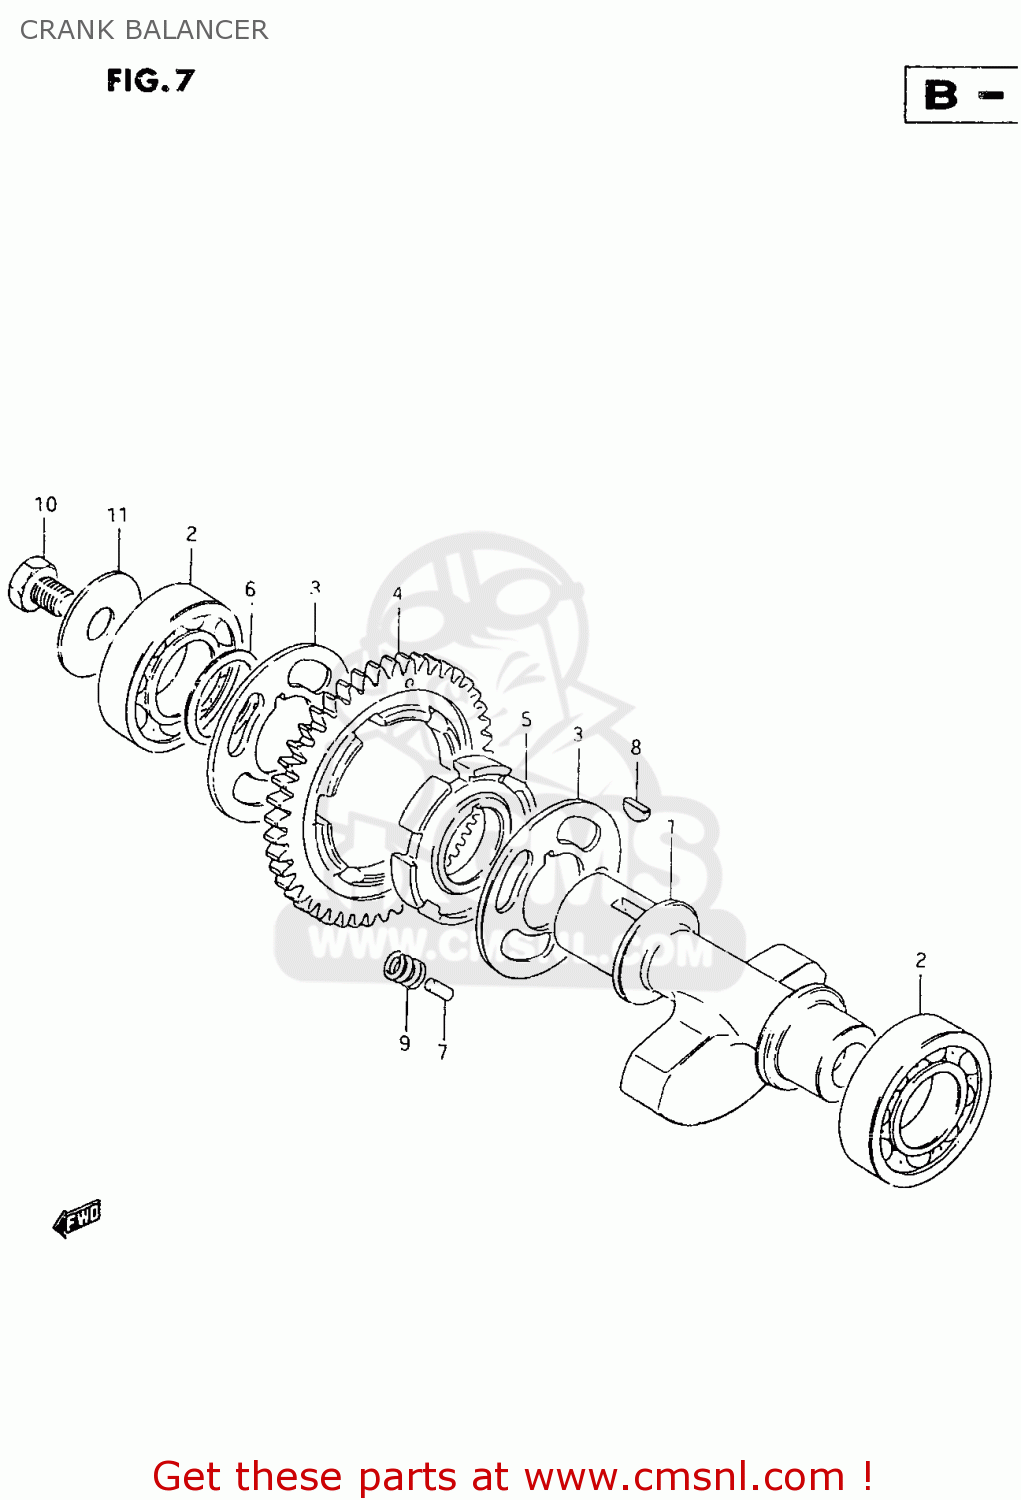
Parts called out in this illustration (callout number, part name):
1	SHAFT,CRANK BALANCER
2	BEARING(25X62X17)
3	WASHER
4	GEAR,CRANK BAL DRIVEN(NT:46)
5	RACE,CRK BAL DRIVEN GR INNER
6	SHIM(25X36X0.5)
7	PIN(4.5X9.5)
8	KEY
9	SPRING
10	Bolt
11	WASHER(12X40X2.5)
